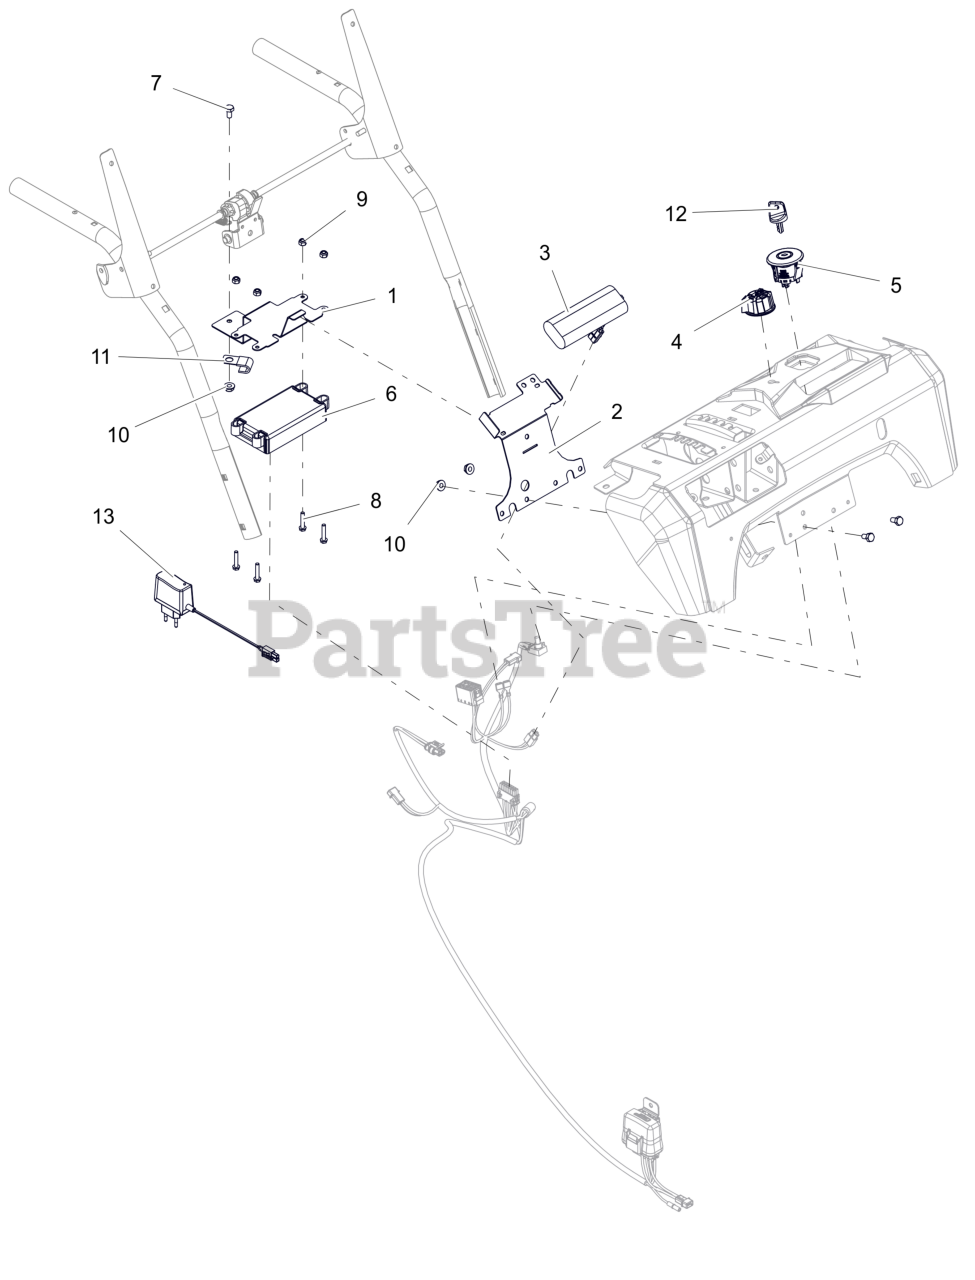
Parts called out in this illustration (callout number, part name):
1	BRACKET, ENGINE EFI-LCT LOWER
2	BRACKET, ENGINE EFI-LCT UPPER
3	BATTERY, SNOW EFI - 7.2V
4	KNOB- CONTROL EFI
5	IGNITION SWITCH ASM - 2 POS
6	ECU SERVICE LCT/CSI - 369CC
7	BLT,HEX .25-20X.50 G5 ZCC
8	BLT, HWH #10-24X1.00 ZCC
9	NUT-LK-NYL #10-24 G2 ZCC
10	NUT-LK-TOP-FLG .250-20 GF ZCC
11	J-CLAMP
12	KEY- IGNITION
13	CHARGER, BATTERY-EFI 7.2V (EU)
